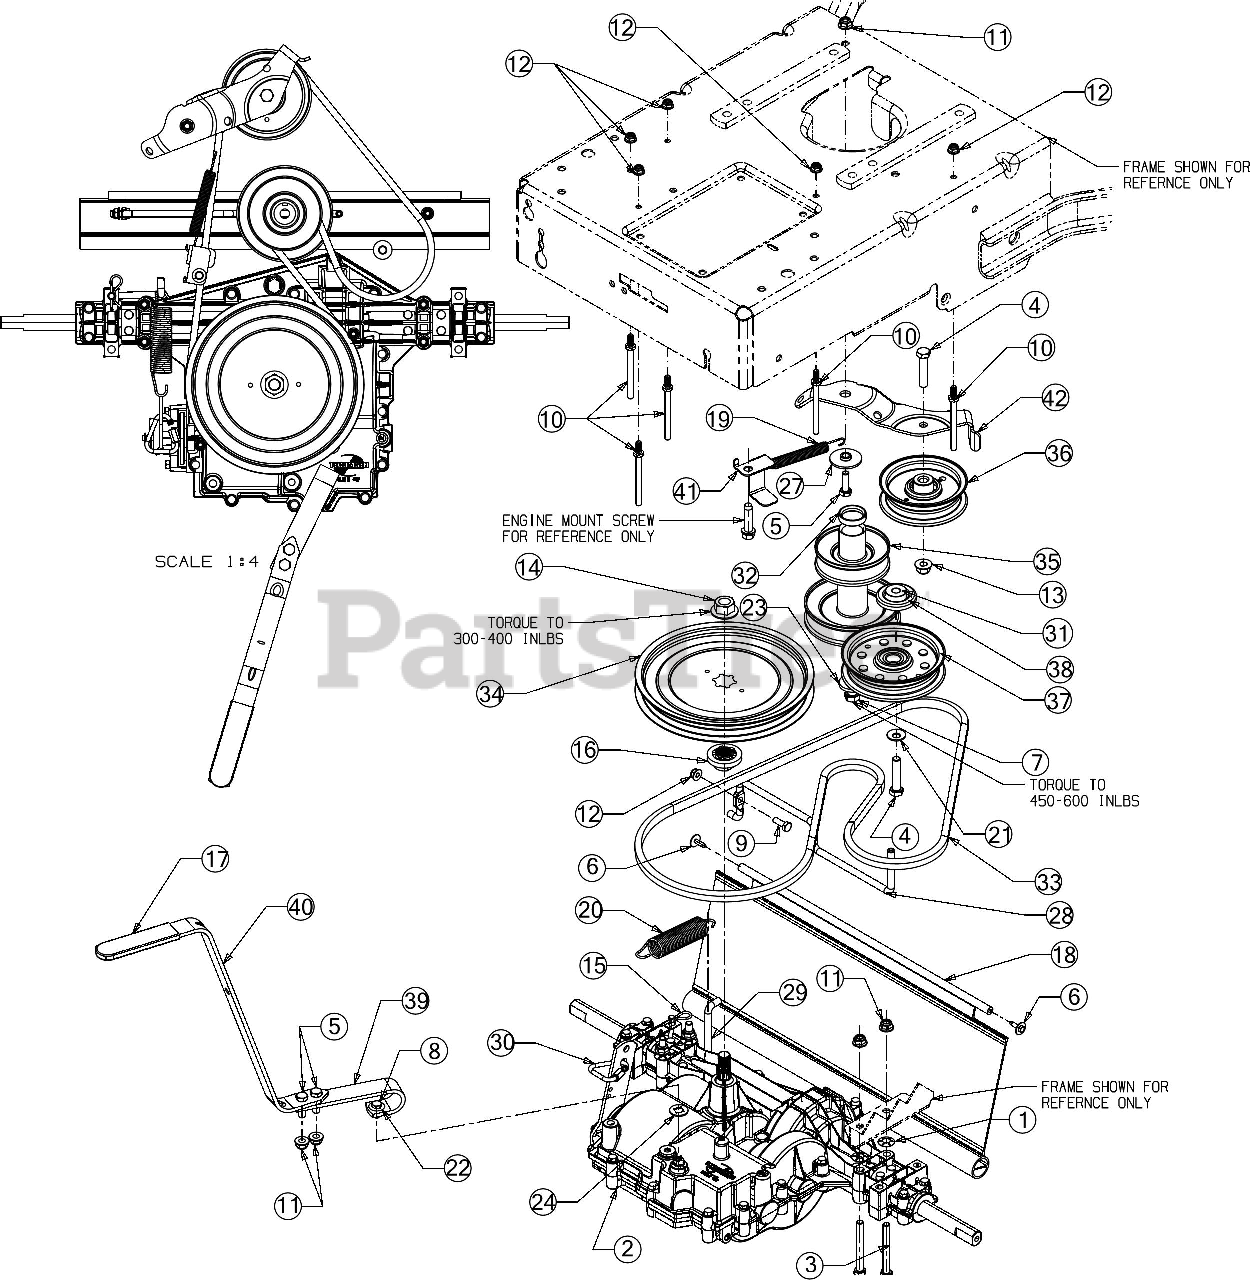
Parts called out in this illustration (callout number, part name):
1	PUSH RETAINER 5/16
2	TRANSMISSION ASSEMBLY
3	HEX SCREW 5/16-18 x 2.75
4	HEX SCREW 3/8-16 x 1.75 GR5
5	SCREW 5/16-18 x 1.0 GR5
6	SCREW 10-16 x .625
7	SCREW 7/16-20 x 3.00 GR5
8	BOLT 1/4-28 x .625 GR5
9	SCREW 1/4-20X.75 GR5
10	BELT KEEPER
11	FLANGE LOCK NUT 5/16-18
12	FLANGE LOCK NUT
14	FLANGE NUT W/HUB
15	INTERNAL COTTER PIN
16	PULLEY HUB
18	WIDECUT TRAILSHIELD
19	EXTENSION SPRING WHEEL DRIVE
20	EXTENSION SPRING
21	BELL WASHER .400 ID x .88 x .060
22	SPRING WASHER BELL
23	FLAT WASHER .445 x 1.248 x .170
24	FLAT WASHER .390X.870X.060
26	GREASE-#251 EP (NOT SERVICEABLE)
27	SHOULDER SPACER
28	BELT KEEPER ROD
29	BRAKE ROD SPRING MOUNT
30	TRI LINK COUPLING
31	SHOULDER SPACER
33	TRANMISSION DRIVE BELT
34	TRANSMISSION PULLEY
35	ENGINE PULLEY
36	IDLER PULLEY
37	IDLER PULLEY 4.25 DIA
38	IDLER PULLEY CAP
39	LOWER SHIFT LEVER
40	UPPER SHIFT LEVER
